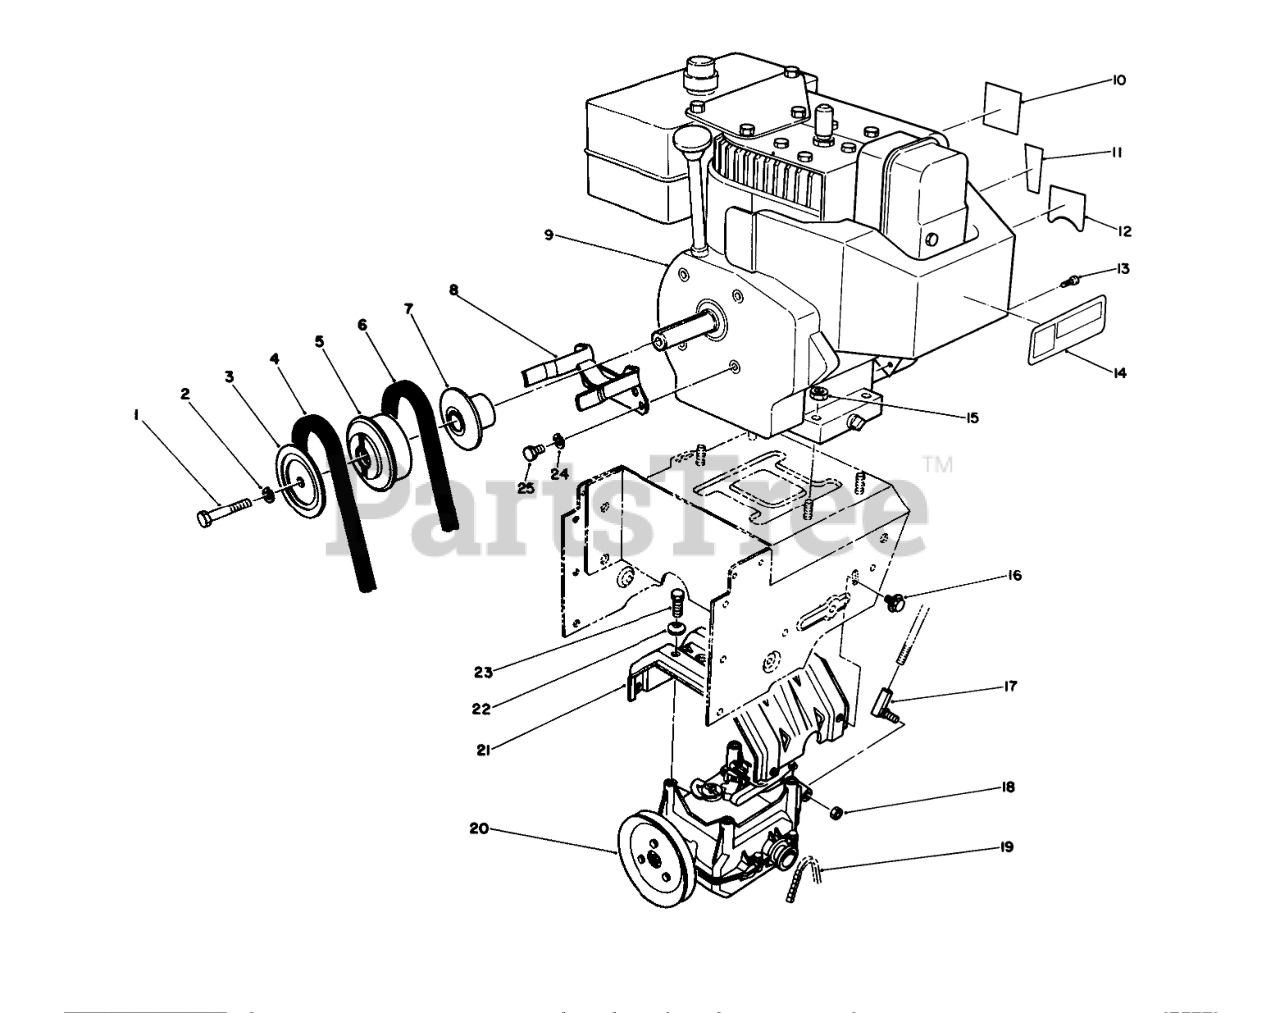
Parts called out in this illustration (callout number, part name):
1	SCREW-HH
2	WASHER-LOCK
3	Sheave Half-Impeller
4	V-BELT
5	LH CASTOR ARM ASM
6	V-BELT-TRACTION
7	TENSION BUSHING
8	Guide-Belt
10	DECAL-PRIMER
11	DECAL-THROTTLE
12	DECAL-CHOKE
13	SCREW-HWH
14	DECAL-WARNING, HOT SURFACE
15	NUT-HF
16	SCREW-HHF
17	JOINT-BALL
18	NUT-LOCK, NI
19	CHAIN
20	TRACTION GEARCASE ASM
21	Frame-Transmission
22	WASHER-SPRING
23	SCREW-HWHTF
24	WASHER-LOCK
25	SCREW-HH
